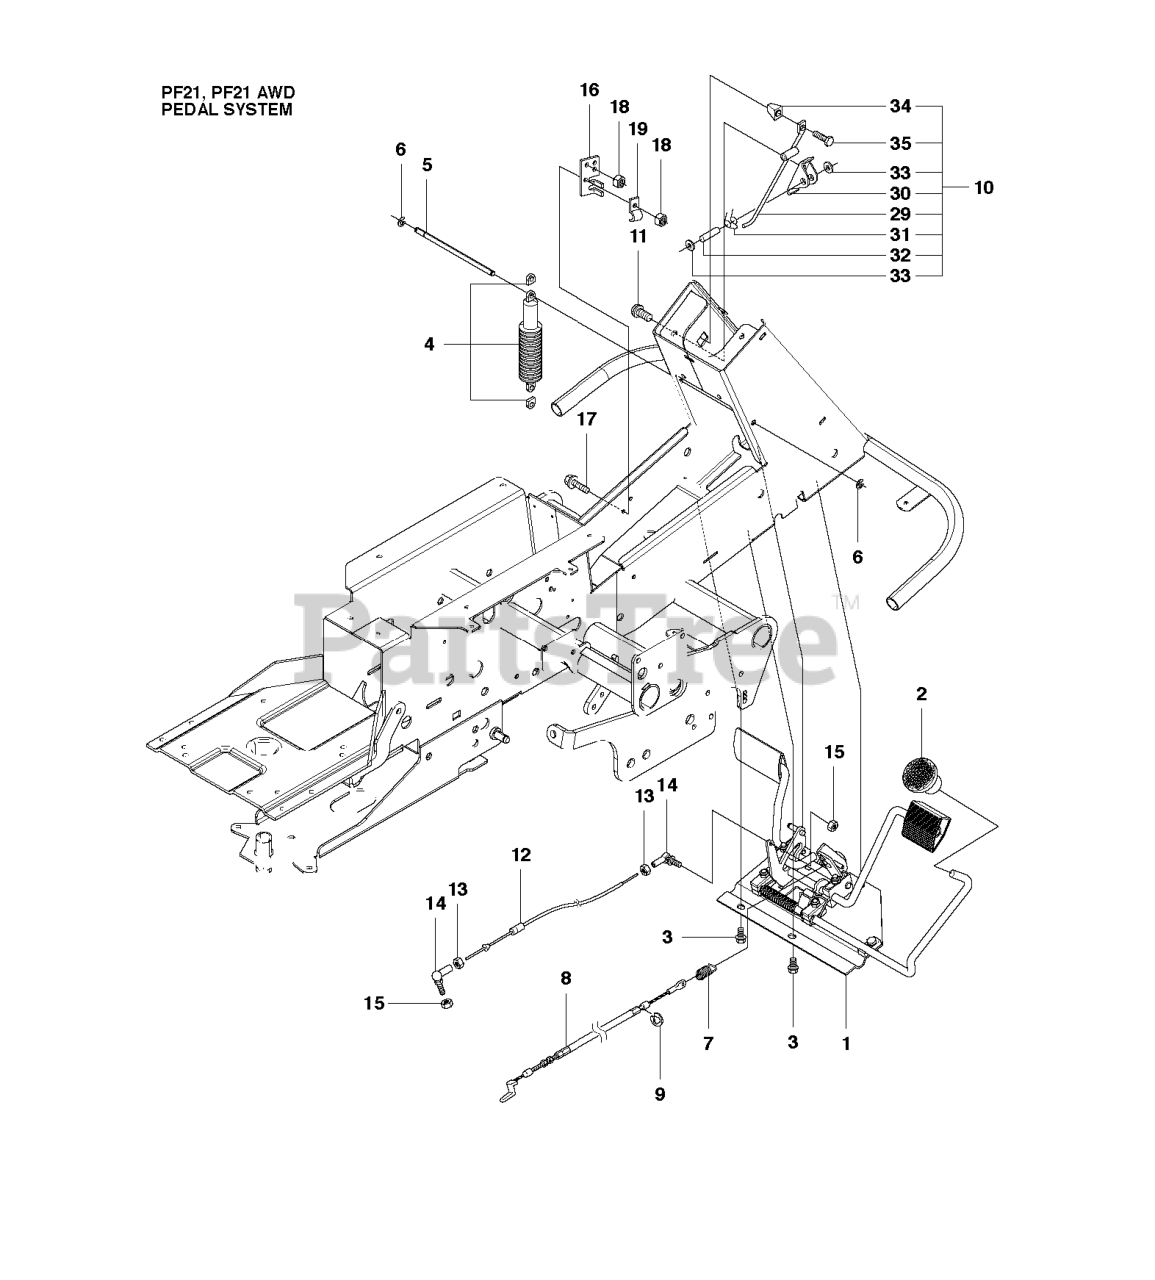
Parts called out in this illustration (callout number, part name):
1	PEDAL ASSEMBLY
2	KNOB
4	SHOCK ABSORBER
8	RP WIRE
12	CONTROL CABLE
14	CONNECTOR
15	LOCKNUT M5
18	LOCKNUT M5
